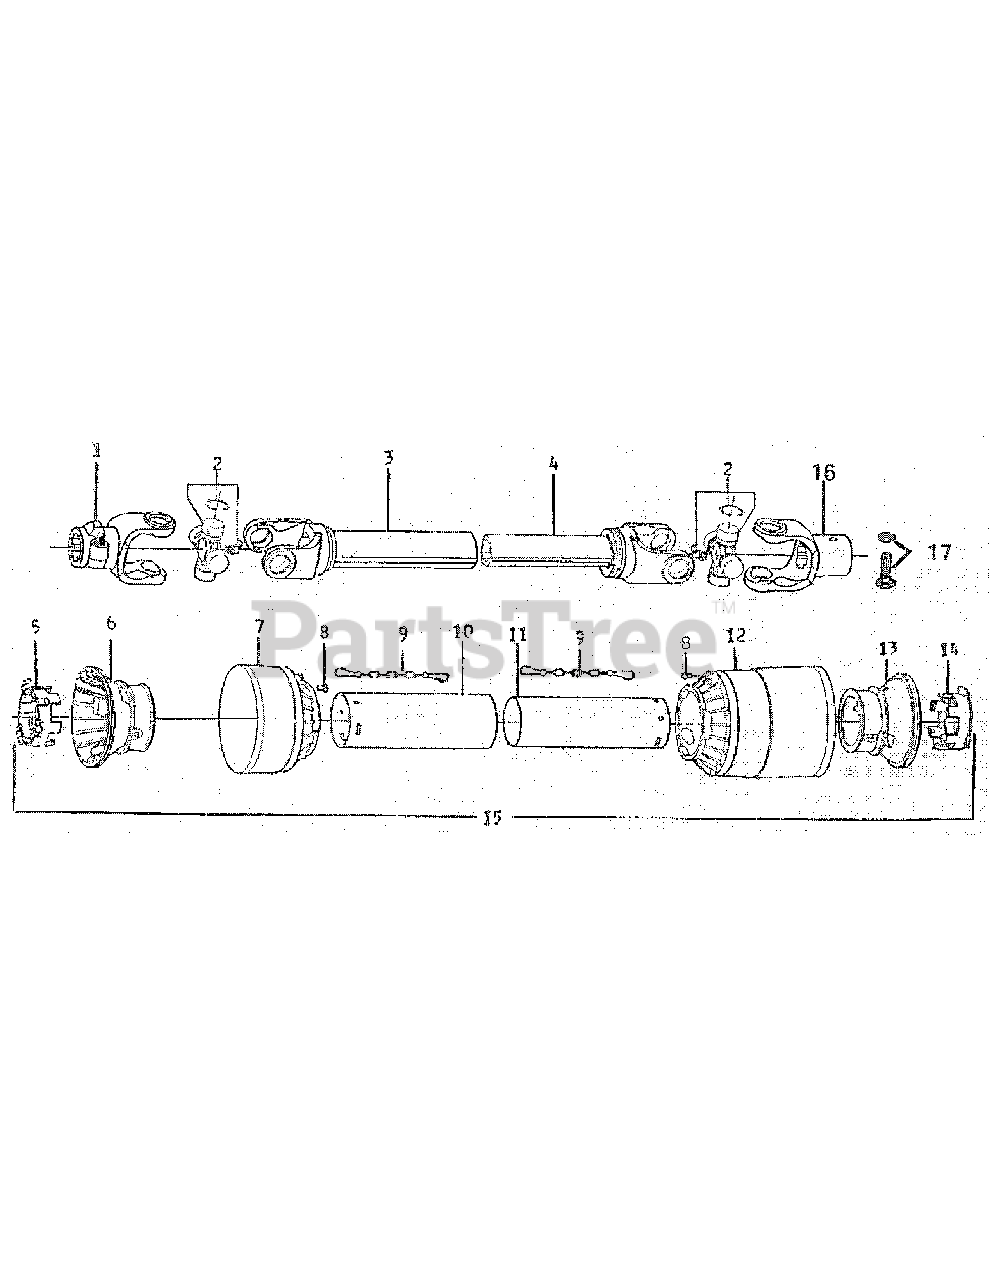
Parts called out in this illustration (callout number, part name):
1	YOKE ASSEMBLY (TRACTOR END)
2	CROSS & BEARING
3	OUTER TUBE W/YOKE
4	INNER TUBE W/YOKE
5	OUTER TUBE BEARING
6	OUTER TUBE RIGID CONE
7	SOFT CONE
8	PIN
9	CHAIN
10	OUTER SHIELD
11	INNER SHIELD
12	SOFT CONE
13	INNER SHIELD RIGID CONE
14	INNER TUBE BEARING
15	COMPLETE PROTECTION
16	YOKE ASSEMBLY (IMPLEMENT END)
17	1/2" X 3.5" SHEARBOLT W/NUT GR2
